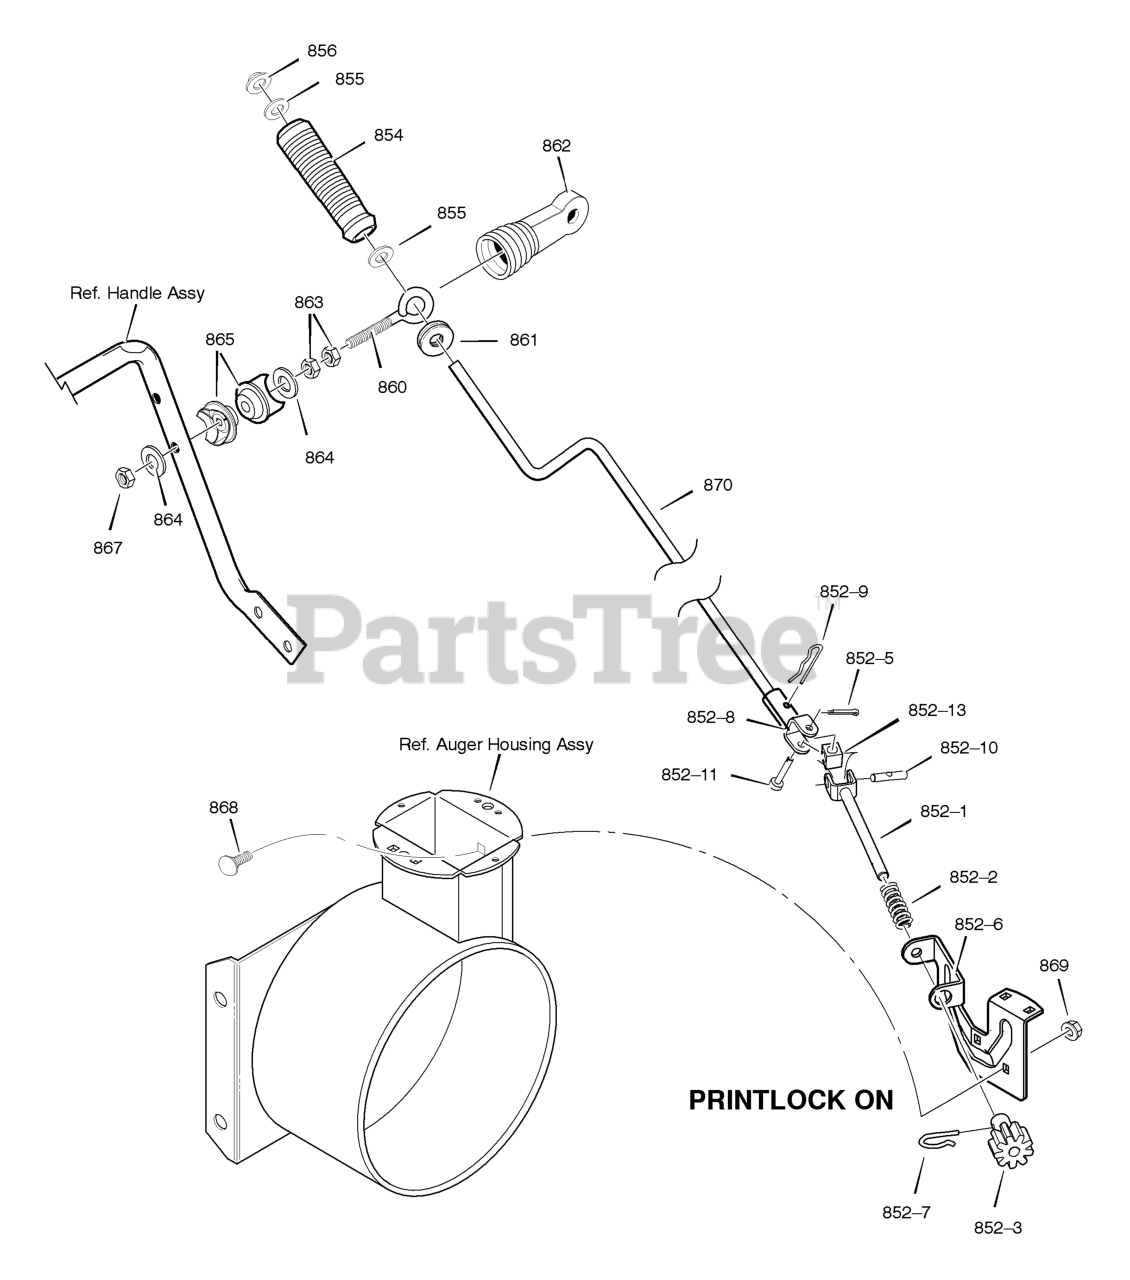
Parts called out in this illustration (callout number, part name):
852-1	ASSEMBLY, YOKE & ROD
852-3	GEAR, CHUTE ROTATION 9T
852-5	PIN, COTTER
852-6	BRACKET, CHUTE GEAR
852-7	PIN, HAIR
852-8	ASSEMBLY, YOKE ADAPTER YZ
852-9	PIN, HAIR
852-10	PIN, UNIVERSAL JOINT
852-11	PIN, CLEVIS
852-13	HOUSING, UNIVERSAL
854	KNOB, SLEEVE
855	FLATWASHER
856	NUT, PUSH ON 3/8"
860	EYE BOLT 3/8-16X6.50
861	GROMMET, EYE BOLT
862	BOOT, EYE BOLT
863	NUT, 3/8-16 HEXJAM
864	FLATWASHER .406X.81X.066
865	ADAPTER, BOOT
867	NUT, 3/8-16 HEXNYL
868	BOLT, CARRIAGE 1/4-20 X 1.00
869	NUT, 1/4-20
870	CRANK, ASSY CHUTE
